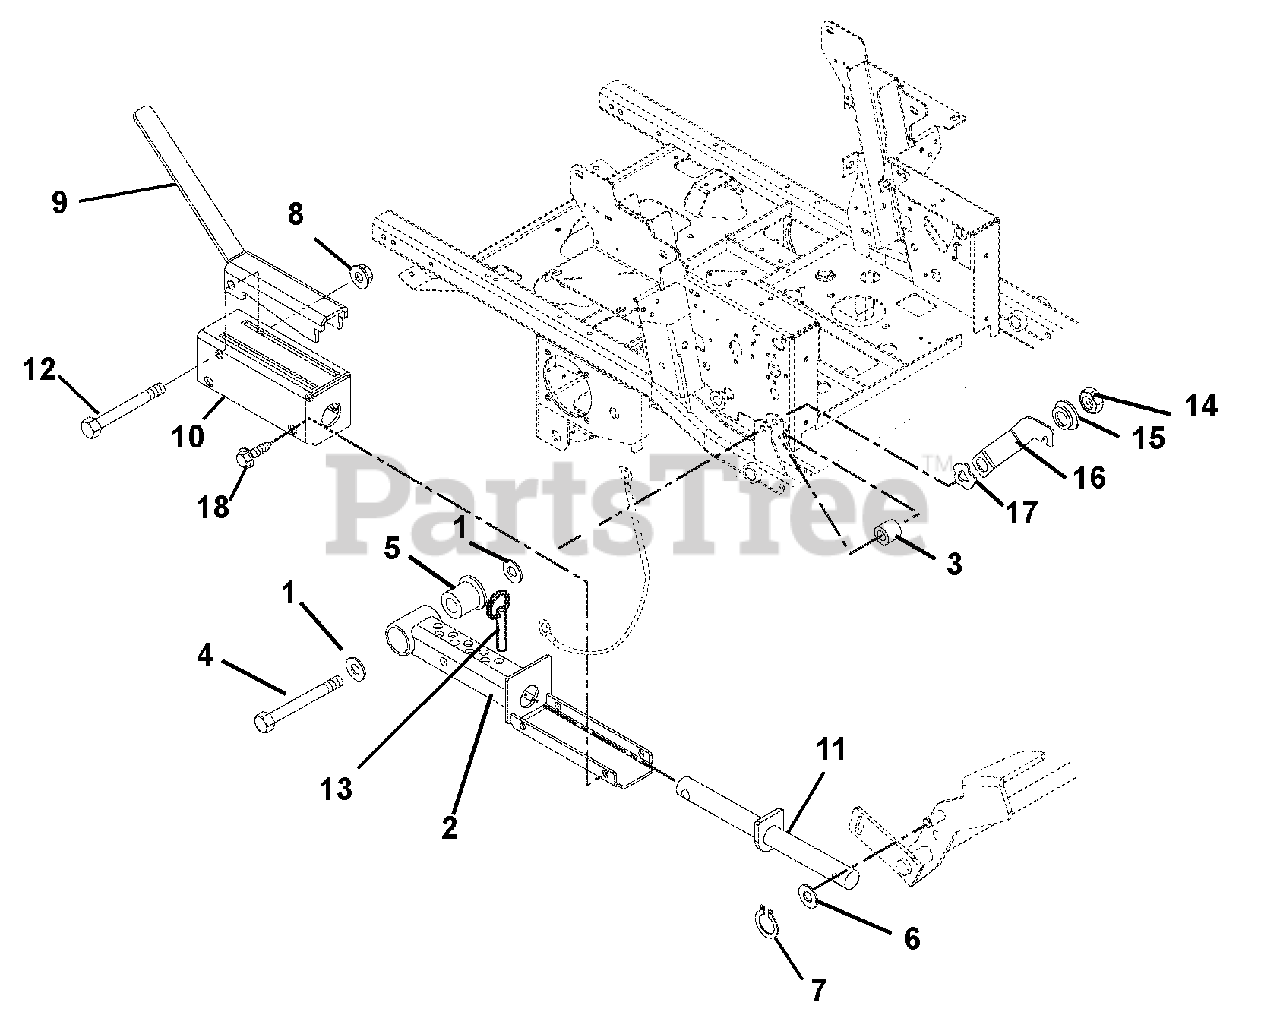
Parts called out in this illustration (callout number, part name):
1	Washer, Flat Steel .531 x 1.25 x .10
2	Weldment, Mechanical Lift
3	Bushing .516 x 1.00 x 1.05
4	Bolt-Hex .50-13 x 5.00 Grade 5
5	Bearing, Pedestal
6	Washer, Flat Steel .656 x 1.31 x .095
7	Ring, Retaining External .625 x .05
8	Nut, Locking Top Flange .38-16
9	Lock-Up, Mechanical Lift
10	Weldment, Mechanical Lift Cover
11	Weldment, Mechanical Lift Shaft
12	Bolt, Hex .38-16 x 3.25 Grade 5
13	Pin, Spring Ball .375 O.D. x 1.50
14	Nut, Locking Top Flange .50-13
15	Bushing-Flange .515 x .750 x .275 x 1.120
16	Latch, Footboard
17	Washer-Wave .076 x 1.120 x .080
18	Screw, Tapping .38-16 x .50 Hex Washer Head
